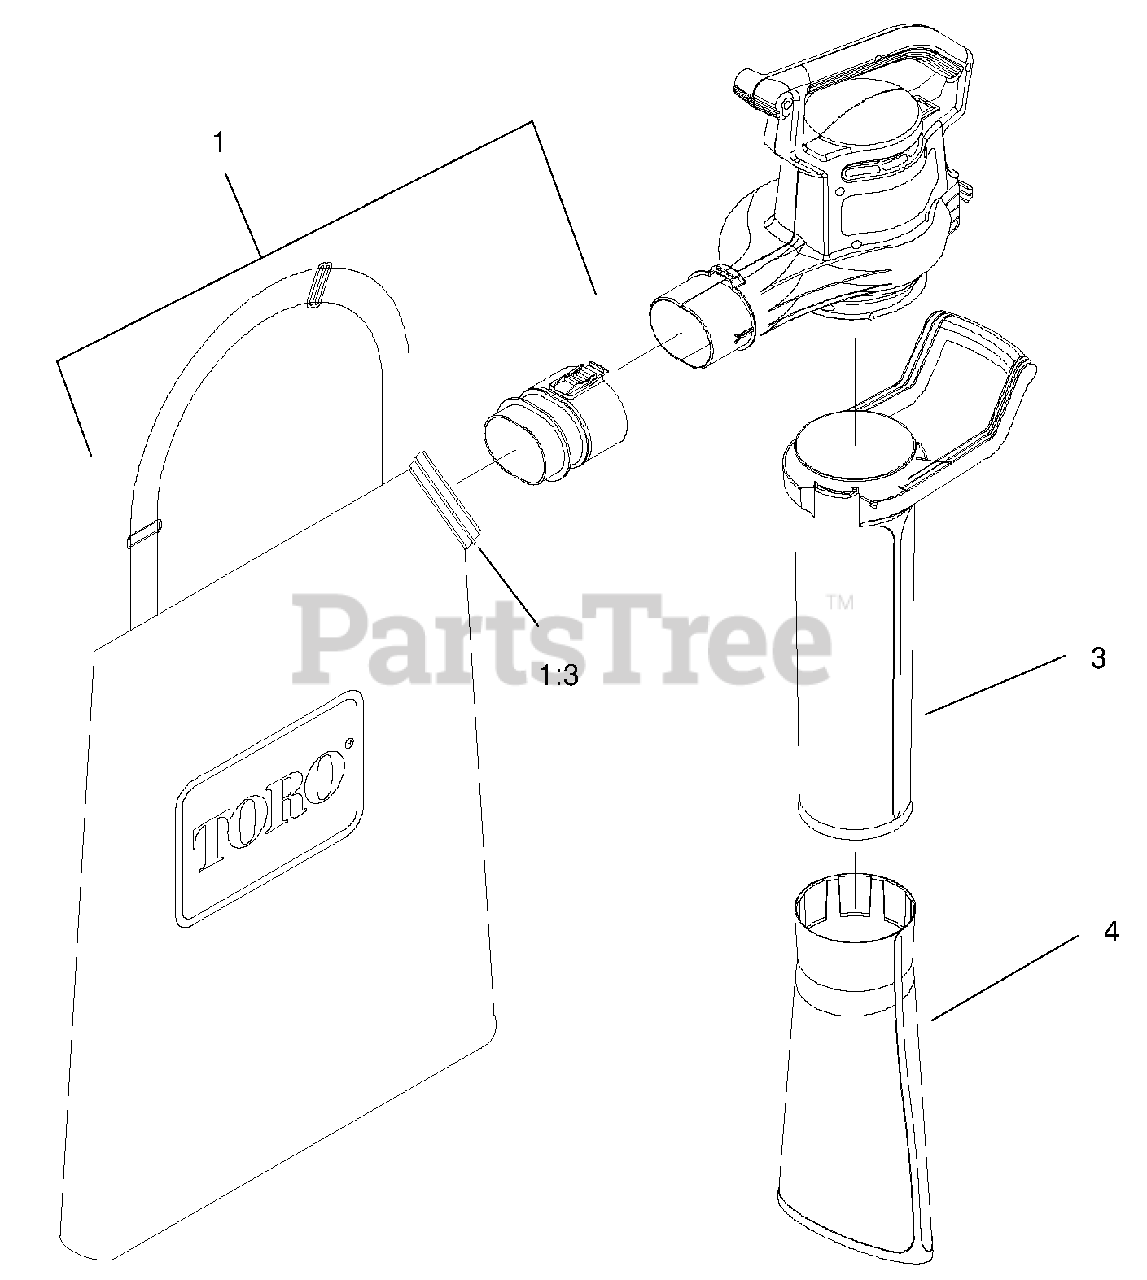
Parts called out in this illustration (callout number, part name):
1:3	Tie-Cable
3	Tube-Vac, Upper
4	Tube-Vac, Lower
